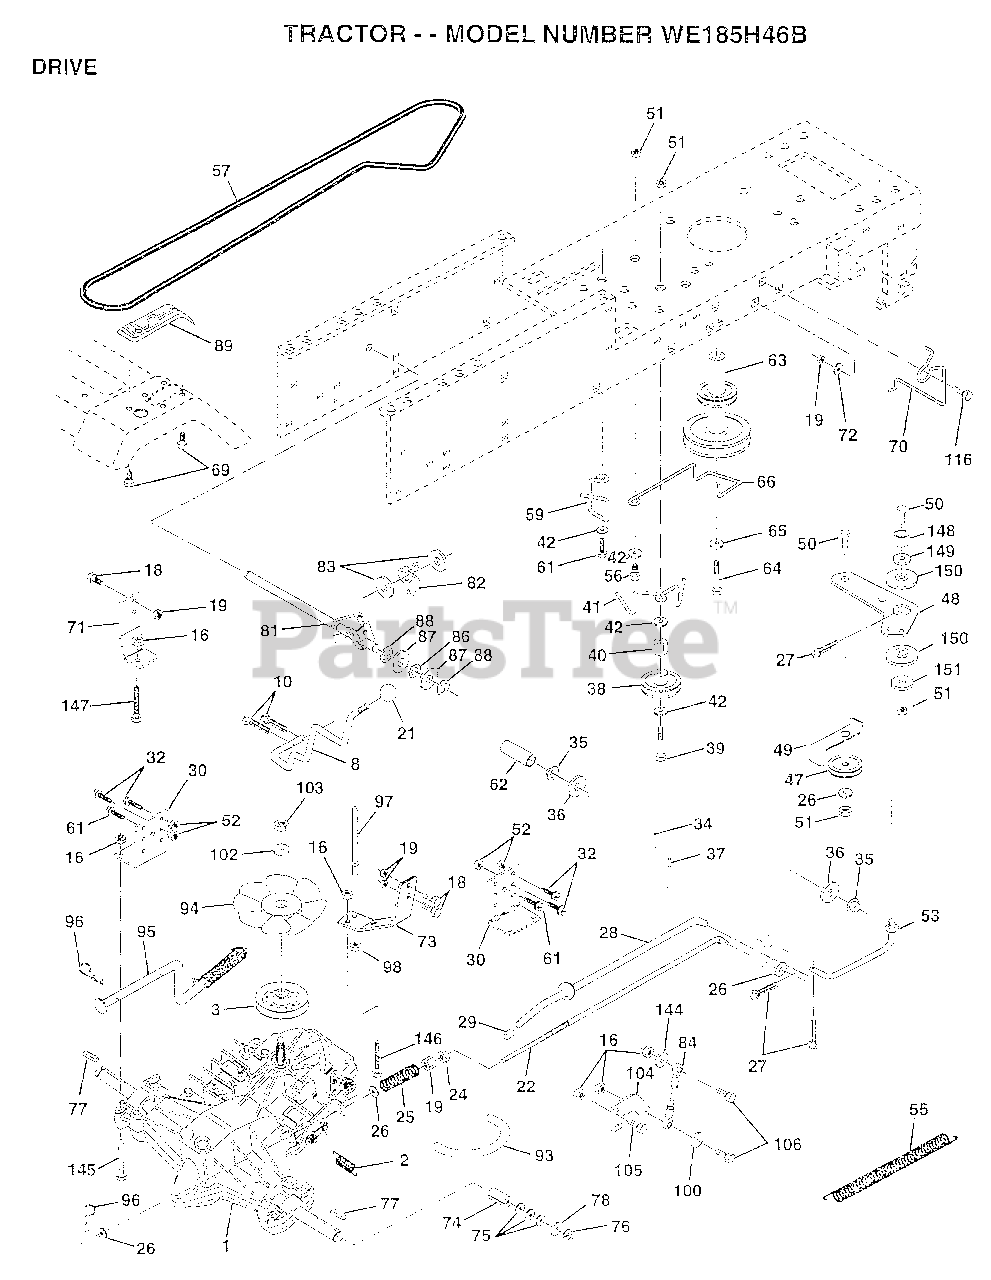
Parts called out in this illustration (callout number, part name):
1	TRANSAXLE.3100650
2	SPRING RET BRAKE
3	PULLEY.TRANSAXLE
8	ROD SHIFT FEND LT
10	PIN COTTER 1/8
16	NUT
18	BOLT
19	NUT
21	KNOB T (1/2-HOLE)
22	ROD.BRAKE.HYDRO.
24	NUT
25	SPRING ROD LT
26	WASHER
27	COTTER PIN
28	ROD.BRAKE.PARK.LT
29	PLUNGER CAP T
30	TRANSAXLE MTG BKT
32	BOLT
34	SHAFT ASM-PEDAL F
35	NYLON BEARING
36	WASHER LT
38	PULLEY.IDLER.FLAT
39	BOLT
40	SPACER T
42	WASHER
48	BELLCRANK.CLUTCH
49	RETAIN BELT
53	"LINK, CLUTCH T"
55	"SPRING, RETURN LT"
57	"BELT.GD DRV 82"""
59	KEEPER BELT CNTSP
61	SCREW
62	PEDAL COVER T
63	PULLEY.ENGINE
64	BOLT
65	LOCKWASHER
66	KEEPER-BELT
69	SCREW HEXWSH H-L
70	"GUIDE.BELT,RH ENG"
71	STRAP TORQ LH HYD
72	WASHER
73	"STRAP-TORQUE,RH"
74	SPACER SPLIT
76	E-RING LT
77	SQUARE KEY
78	WASHER
81	SHAFT.CROS.20.HYD
82	"SPRING,TORSION"
83	WASHER
84	ROD.TIE
86	BUSHING
87	WASHER D
88	KLIP RING
93	"LINE FUEL HYD 4"""
94	"FAN 7"" HYDRO"
97	BOLT KEEPER RH
98	NUT
100	WASHER M
102	WASHER BELLEVILLE
104	ARM CONTROL HYDRO
105	SCREW CAP 5/16-18
106	BOLT
116	BOLT RDHD 3/8-16
144	WASHER
145	BOLT.HEX.FLGHD
146	BOLT.HEX.FLGHD.
147	BOLT.HEX.FLGHD
149	SPACER RETAINER
150	BUSHING.NYLON
151	WASHER
